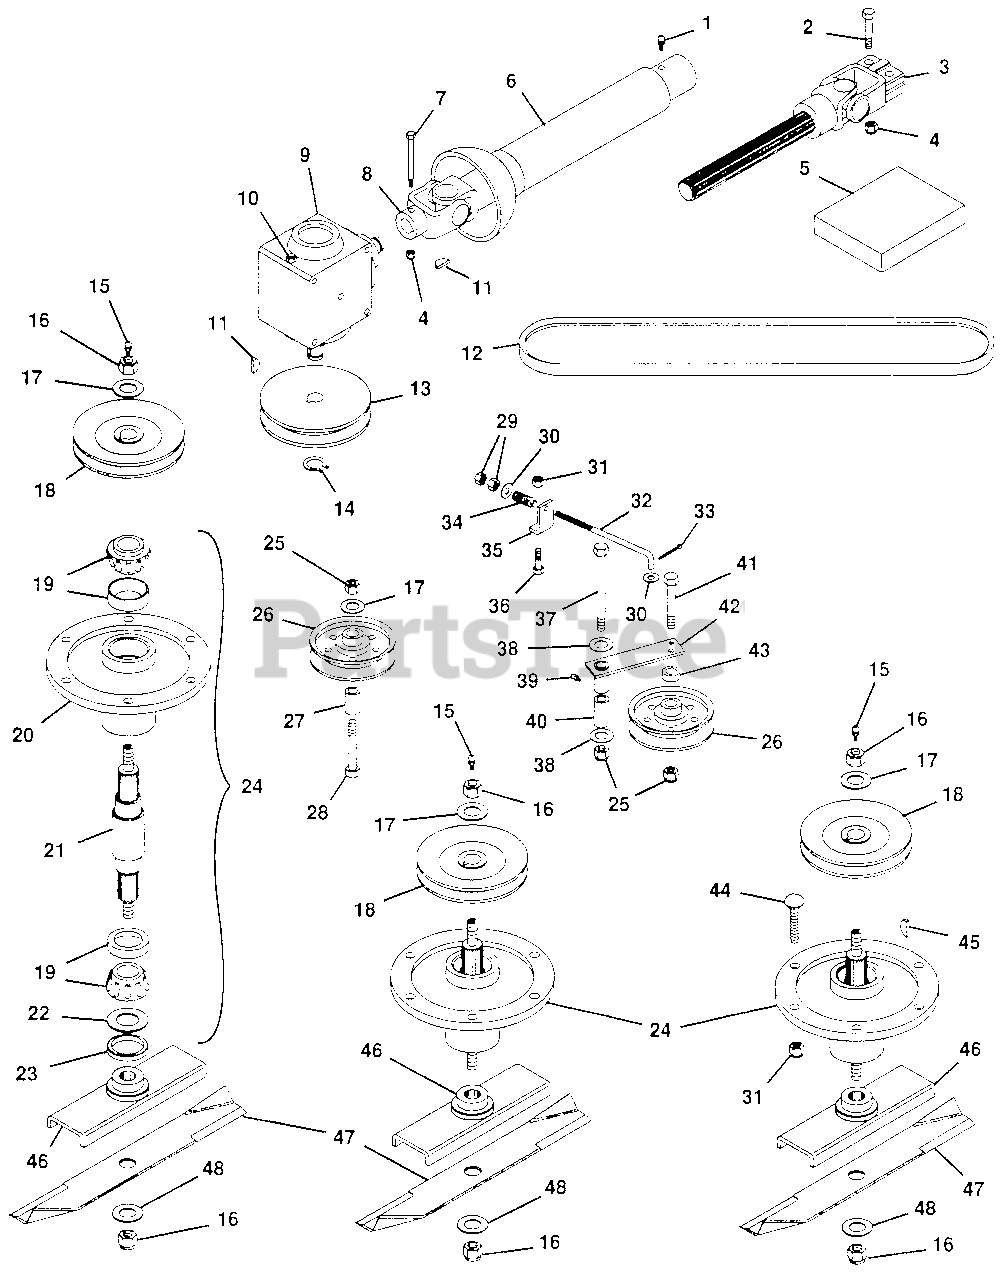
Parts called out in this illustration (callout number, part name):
1	Fitting, Lube 1/4-28
2	Bolt, Hex 5/16-18x1.75
3	Assembly, U-Joint Male
4	Nut, Lock 5/16-18
5	Kit, Repair U-Joint
6	Assembly, U-Joint Female
7	Bolt, Hex 5/16-18x2.25
8	Yoke
9	Gearbox, Right Angle 1:1
10	Plug, 1/8 Vent
11	Key, Woodruff .25x.875 Hard #A
12	Belt, Vee 72" Mower
13	Sheave, Gear Box
14	Ring, Retaining .875 Shaft
15	Fitting, Lube 1/8
16	Nut, Lock 5/8-11
17	Washer, Flat .687x1.312x.122
18	Weldment, Spindle Sheave
19	Assembly, Bearing
20	Housing, Bearing
21	Shaft, Spindle
22	Washer, Flat .975x1.970x.030
23	Seal, Steel
24	Assembly, Spindle
25	Nut, Lock 1/2-13
26	Pulley, Flat Idler
27	Bush., St. .562x.975x1.00 Stl.
28	Bolt, Hex 1/2-13x2.75
29	Nut, Hex 3/8-24
30	Washer, Flat .406x.812x.065
31	Nut, Lock 3/8-16
32	Rod, Idler
33	Pin, Cotter .09x.75
34	Spring, Comp 1x.78x338
35	Support, Spring "B"
36	Bolt, 3/8-16x1.125
37	Bolt, Hex 1/2-13x3.75
38	Washer, Flat .500x1.250x.083
39	Fitting, Lube 1/4-28
40	Bush., St. .505x.855x2.50 Stl.
41	Bolt, Hex 1/2-13x2.00
42	Weldment, Idler Pivot
43	Bush., St. .516x.875x.300 Stl.
44	Bolt, 3/8-16x1.37 Rd Hd Sq Nk
45	Key, Woodruff .25x1.00 Hard #15
46	Weldment, Blade Cradle
47	Blade, 72" Mower
48	Washer, Flat .656x1.312x.095
